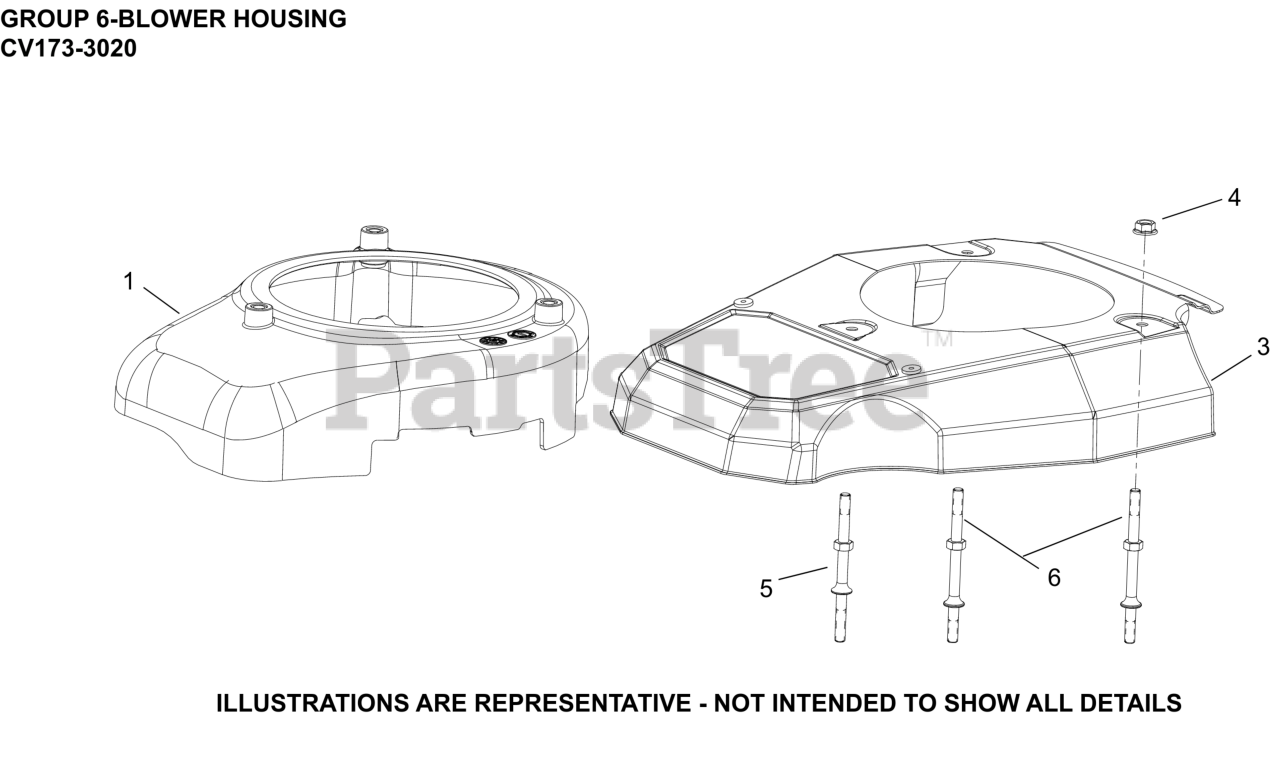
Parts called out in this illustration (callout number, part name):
1	KIT, BLOWER HOUSING
3	COVER, ENGINE
4	NUT, HEX FLANGE (M6) - USE 14 100 16-S
5	STUD-USE 14 072 25-S
6	STUD, BLOWER HOUSING
